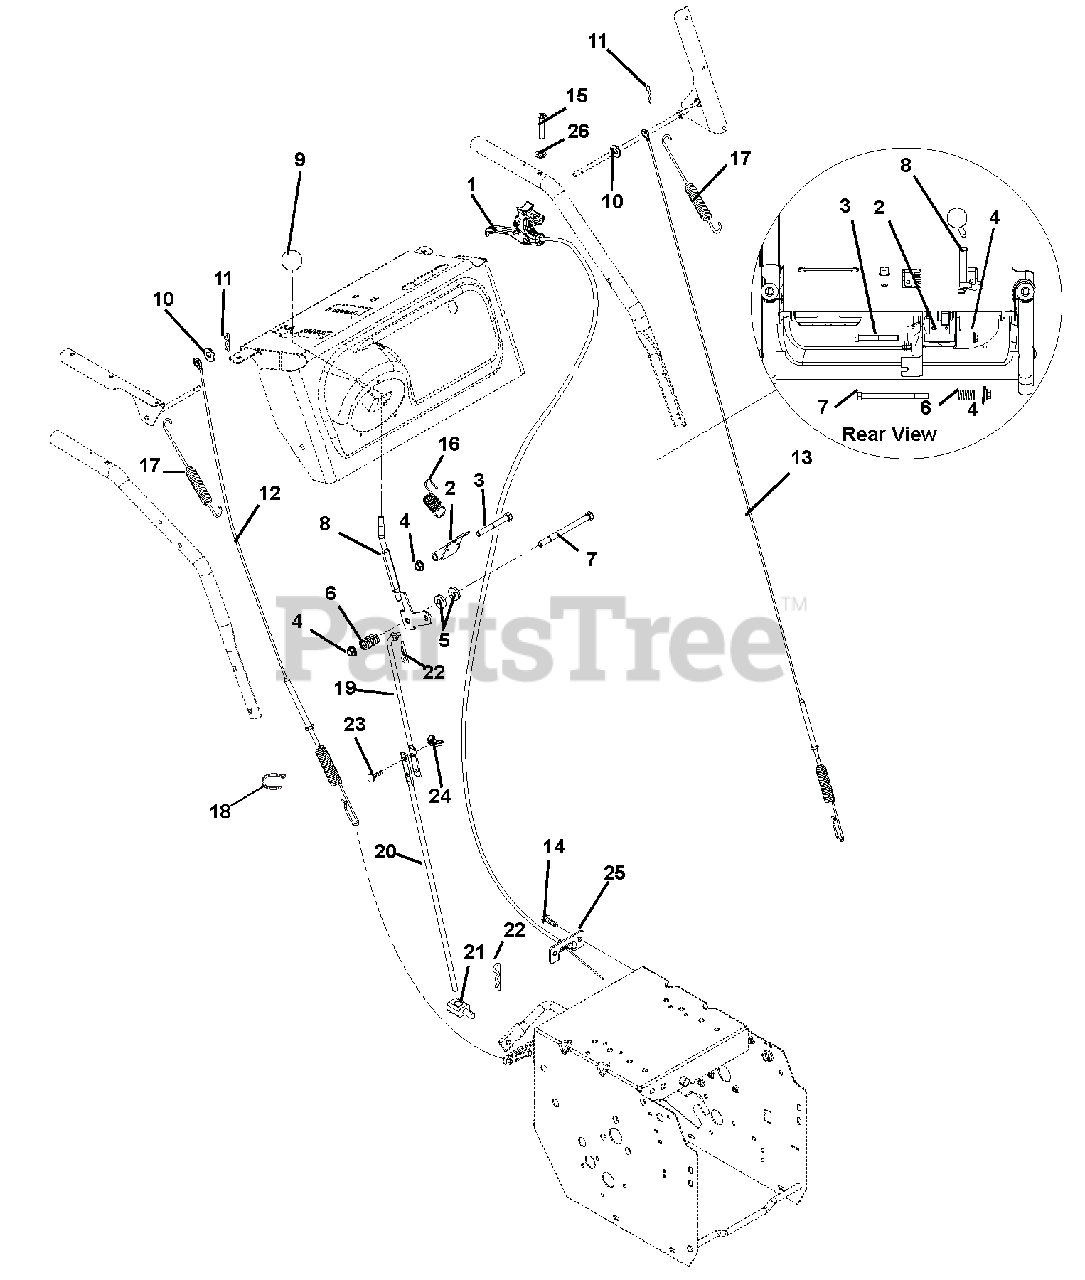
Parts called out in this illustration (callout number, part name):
1	CABLE-TRIGGER-REMOTE WHEEL-DEL
2	ARM, INTERLOCK
3	@BLT-HEX .38-16X3.00 GR5 YWZC
4	@NUT-LK-TOP-FLG .38-16 YWZC
5	WSHR-FL-STL .406X1.00X.188 YWZ
6	SG-COMP .125X.781X1.250
7	@BLT-HEX .38-16X5.00 GR5 YWZC
8	LEVER, SHIFT
9	KNOB,BALL -BLACK 1.47" .375-16
10	@WSHR-FL-STL.281X.62X.065 YWZC
11	PIN-HAIR INT .06X.18X.77
12	CABLE, ATTACHMENT
13	CABLE, TRACTION - DELUXE
14	SCR-TAP .25-20X.50 HWH TR YWZ
15	SCR-MCH .25-20X1.50 OVAL HD
16	SPRING-EXT .047X.438X1.45
17	SG-TENS .056X.60X4.40
18	CABLE TIE LG 5-1/2
19	ROD, SHIFT-UPPER
20	ROD, SHIFT-LOWER
21	PIVOT,SHIFT ROD .375-16(TRUNN)
22	PIN-HAIR, ENDRIES #25 YWZC
23	@BLT-RDHDSQNK .25-20X.75 G5YZ
24	NUT-LK WING .250-20 YWZC
25	BRACKET, CABLE MOUNT
26	WSHR-LK-INT .250 TH TYA
